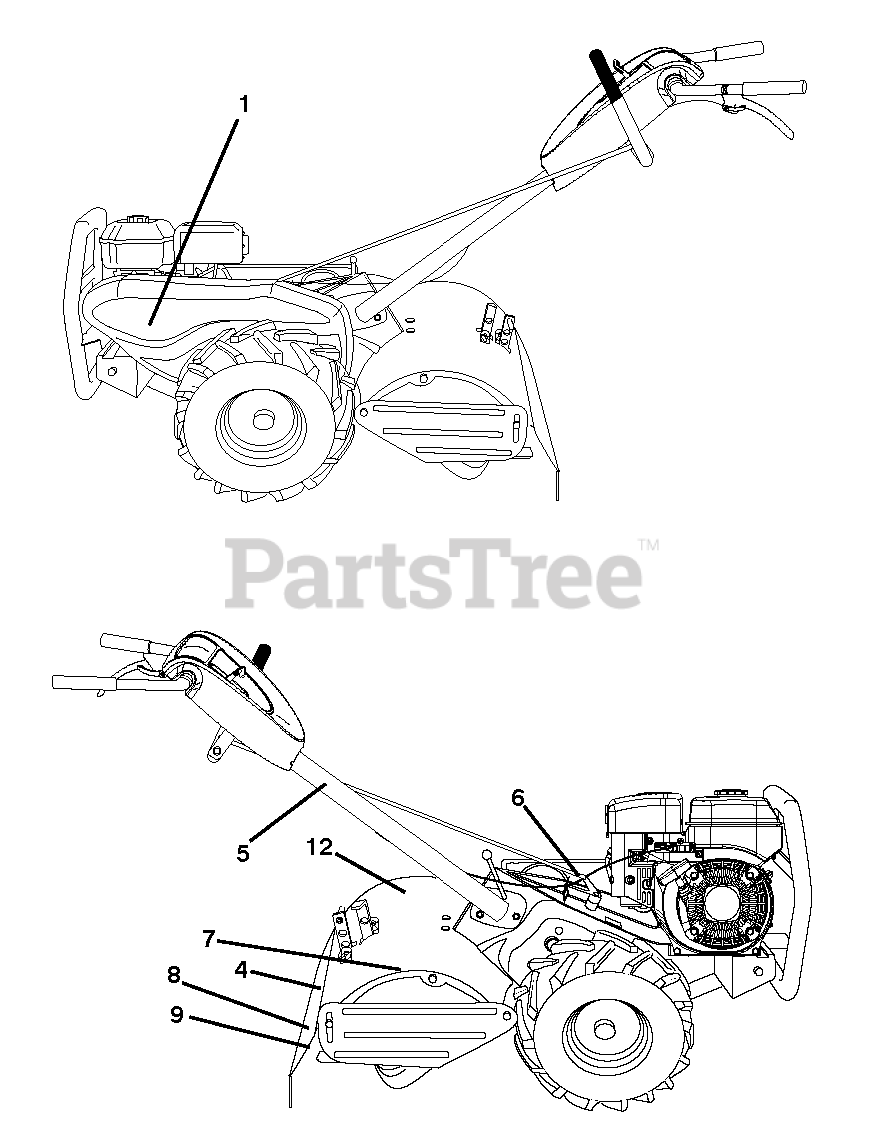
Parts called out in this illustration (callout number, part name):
1	RP.DECAL.BADGE.170MM.TEXTLOGO
4	DECAL.SHIELD.TN.DRT.REAR.SY
5	DECAL.PLACEMENT.HAND.SYMBOLS
6	DECAL.SHIFT.INDICATOR.DRT
7	DECAL.TILLER.RDIRSYMBL.ORG.HUS
8	DECAL EUROPE STANDARD CE
9	DECAL.WARNING.4-SYM.TILLER.INT
12	DECAL.TILLER.FDIRSYMBL.ORG.HUS
